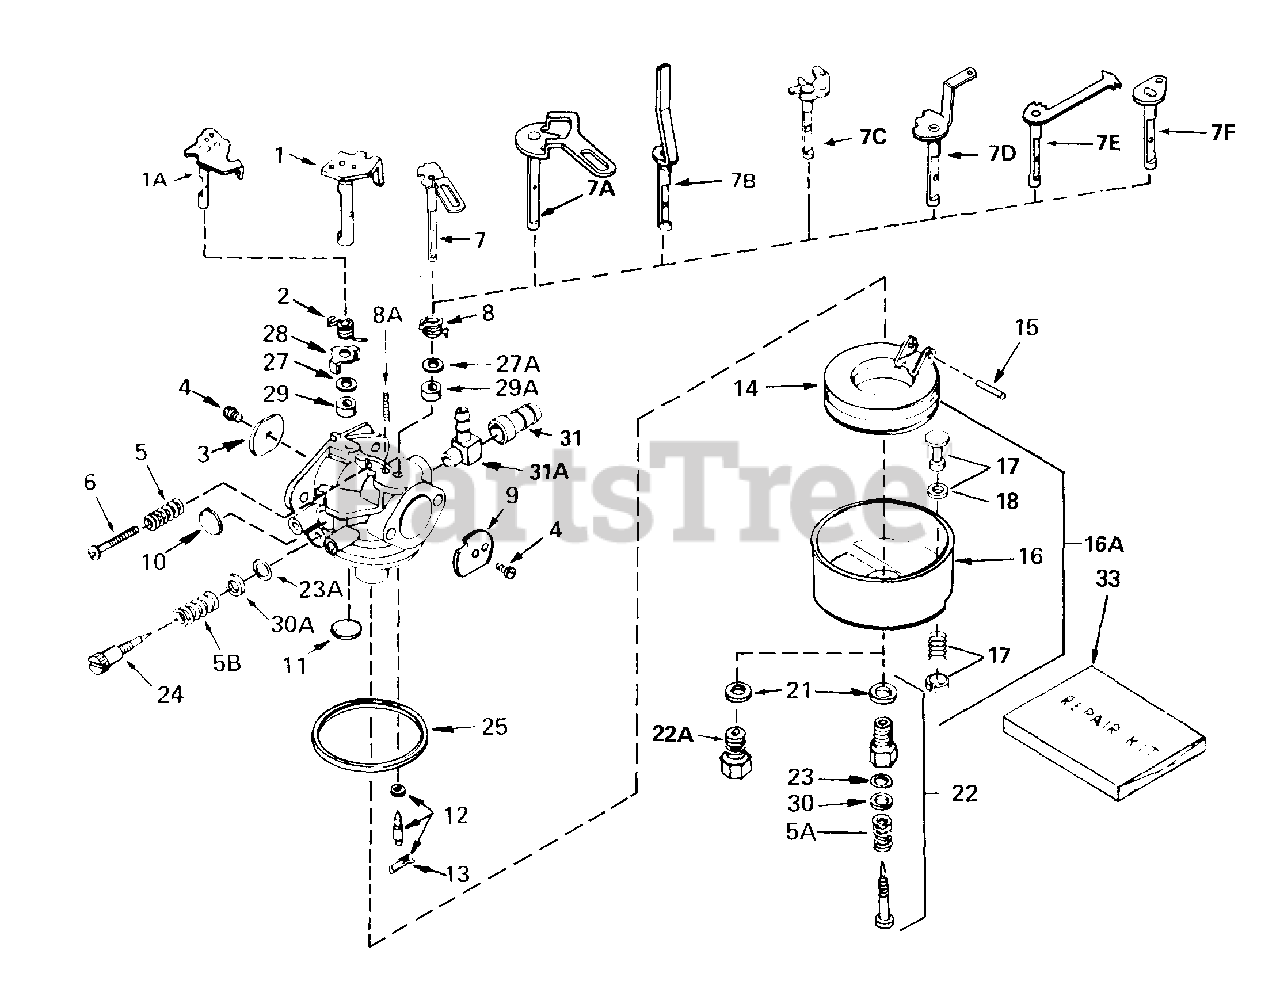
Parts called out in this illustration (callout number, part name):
1	"Shaft & Lever Assy., Throttle
2	Spring, Throttle return
3	Shutter, Throttle
4	Screw, Throttle & Choke shutter
5	Spring, Adj.
5A	Spring, Adj. screw
5B	Spring, Adj. screw
6	Screw, Idle regulating
7C	Shaft & Lever Assy., Choke
8	Spring, Choke return
9	Shutter, Choke
10	Plug, Welch
11	Plug, Welch
12	Inlet Needle, Seat & Clip Assy.
13	Clip, Inlet needle
14	Float, Carburetor
15	Shaft, Float
16	Bowl, Float
21	Gasket, Bowl-to-body
22	Adj. Screw Assy., Main
23	"O" Ring, Adj. screw
23A	"O" Ring, Adj. screw
24	Screw, Idle adj.
25	Gasket, Bowl-to-body
28	Retainer, Seal
29	Seal, Dust
29A	Seal, Dust
30	Washer, Flat
30A	Washer, Flat
31A	Fitting, Fuel
33	Repair Kit
